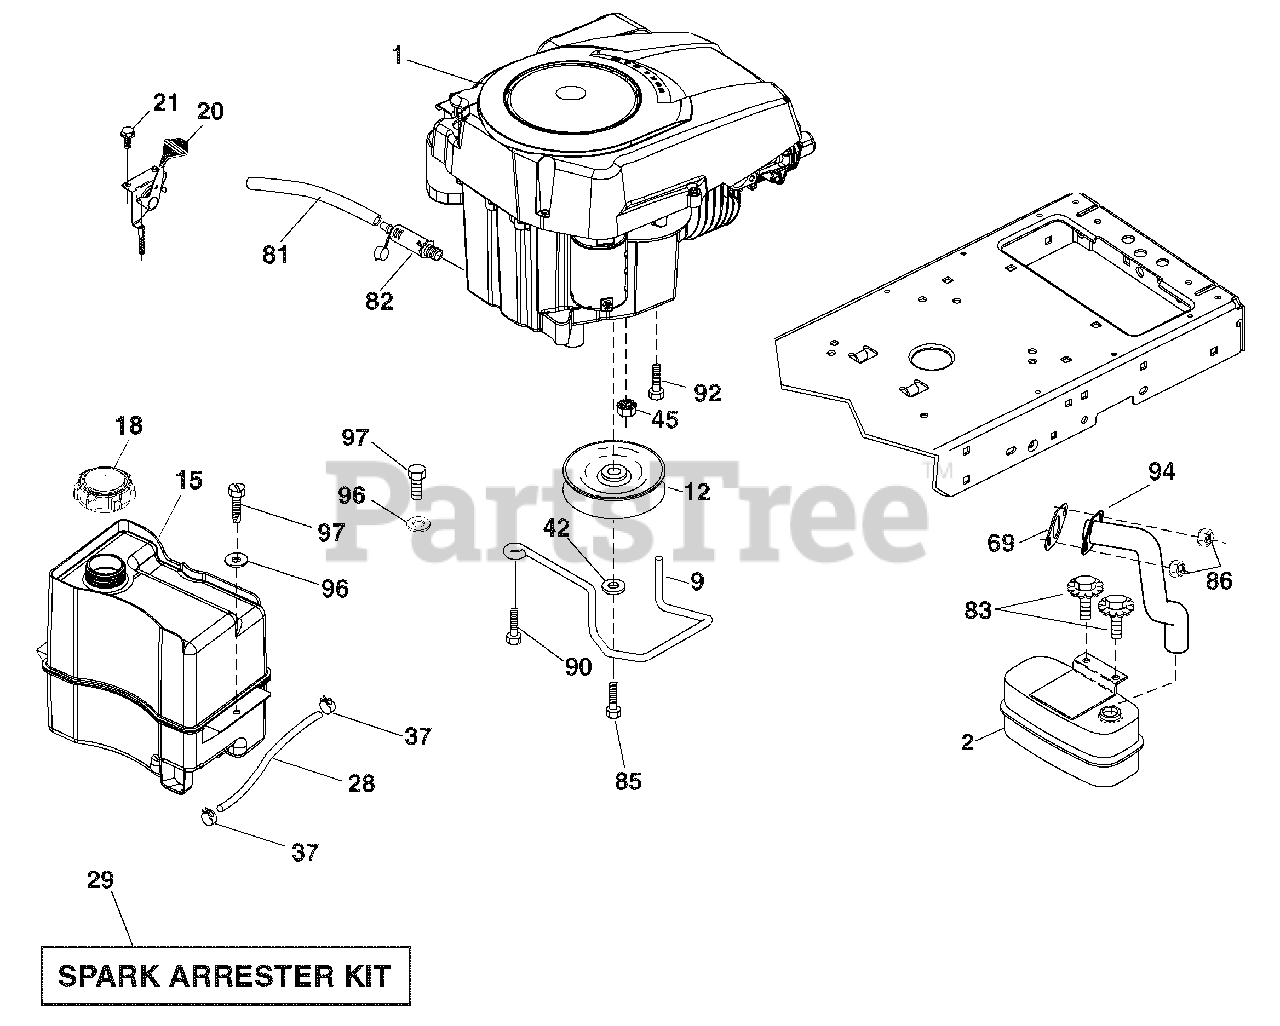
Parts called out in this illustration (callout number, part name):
9	Keeper Belt Engine
12	Pulley Engine
15	Tank Fuel
18	Cap Asm
20	Control Throttle
21	Screw 10 x 3/4 Single Lead Hex
28	Fuel Line
29	Spark Arrester Kit
37	Clamp Hose
42	Washer Lock 7/16
45	Nut Keps Hex 1/4-20 unc
79	Screw Socket Head 5/16-18 x .75
81	Tube Drain Oil Easy
82	Plug Drain Oil
83	Bolt 5/16-18 UNC x 3/4 w/Sems
85	Bolt Hex 7/16-20 x 4 x Gr. 5-1.5 Thr
86	Nut Hex Flange Toplock M8-1.25
90	Screw 3/8-16 x 1
92	Screw 3/8-16 x 1
94	Tube Exhaust
96	Washer 9/32 x 7/8 x 16 Ga.
97	Screw 1/4-20 x 3/4
